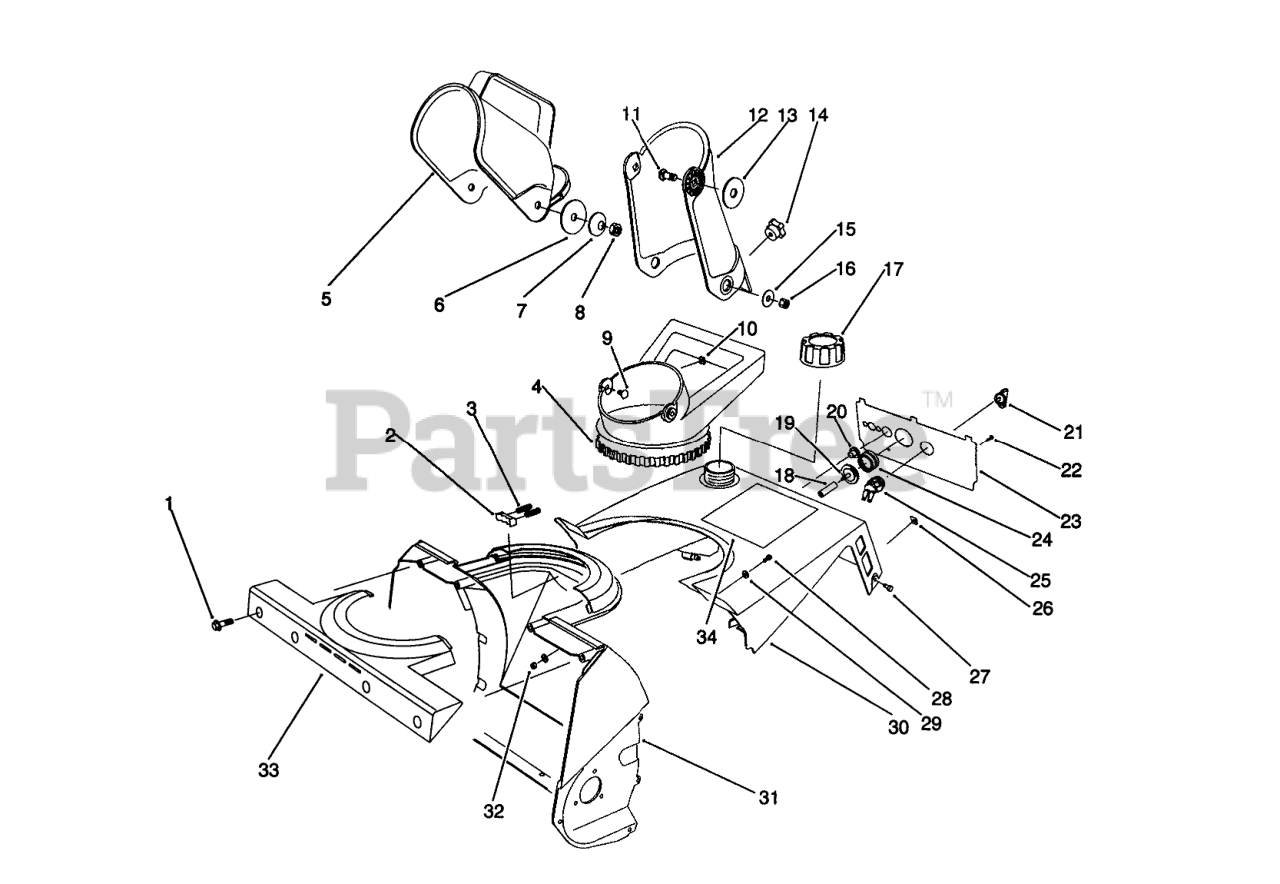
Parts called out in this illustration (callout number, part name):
1	SCREW-PLASTIC
2	DETENT-CHUTE
3	SPRING-COMPRESSION
4	HANDLE-CHUTE
5	DEFLECTOR-CHUTE
6	WASHER-FLAT
7	WASHER-BELLEVILLE
8	NUT-LOCK, NI
9	SCREW-CARR
10	PUSHNUT-RETAINER, BOLT
11	BOLT-CARR
12	Chute
13	Washer-Rubber
14	KNOB-CHUTE
15	WASHER-FLAT
16	NUT-KEPS
17	GAS CAP ASSEMBLY
18	HOSE-PRIMER
19	BODY-PRIMER
20	GUIDE-ROPE, STARTER
21	KEY-IGNITION
22	SCREW-SHWH, THREAD FORMING
23	CNTRL PNL/SILK SCRN
24	BULB-PRIMER
25	SWITCH
27	SCREW-THREAD FORMING
28	SCREW-PPH
29	WASHER-FLAT
30	Shroud-Upper
32	NUT-LOCK, NI
33	RETAINER-CHUTE
34	DECAL - POWERLITE REC.
